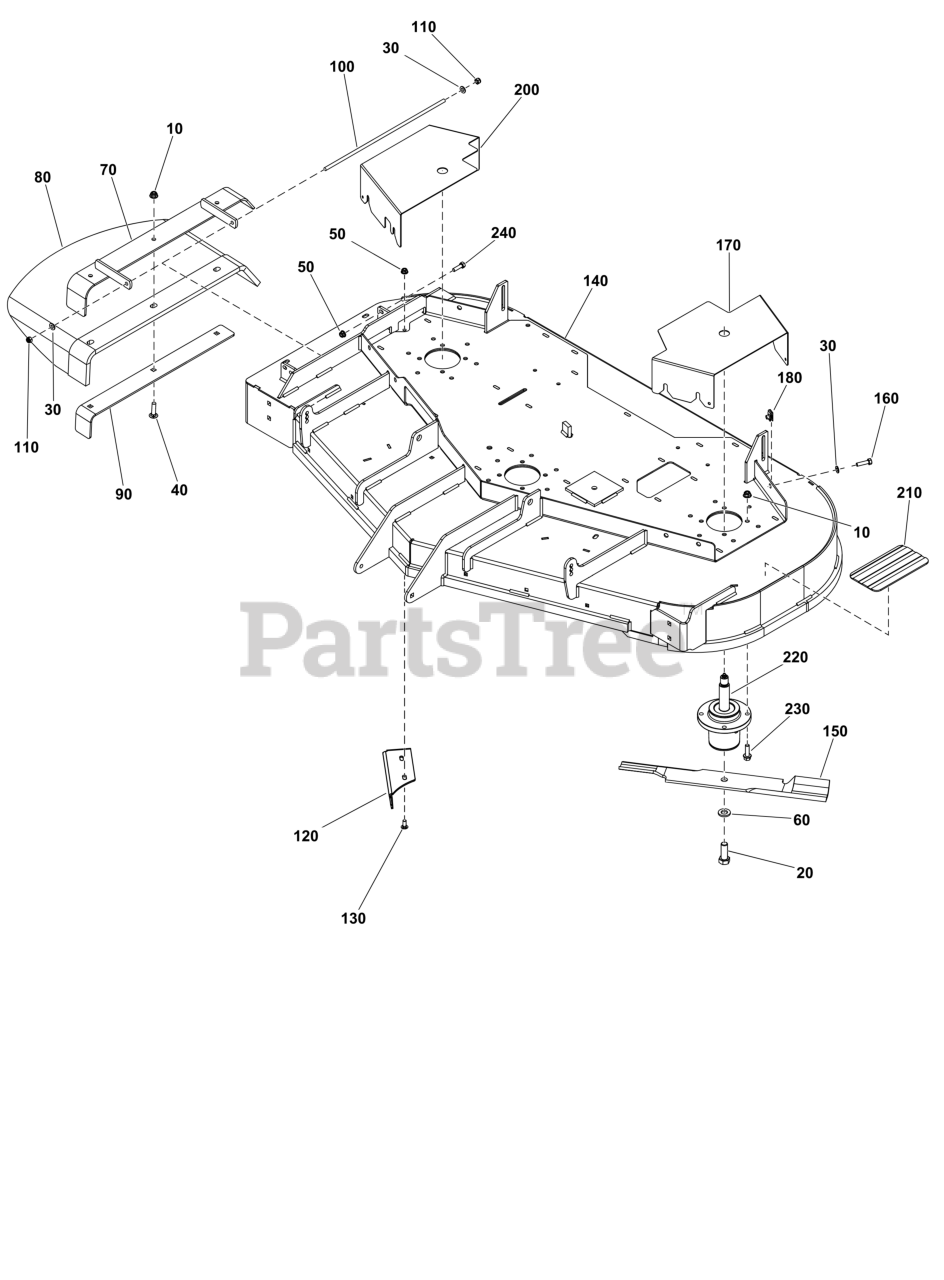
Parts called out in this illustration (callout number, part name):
10	NUT, 3/8-16 HEX NYLOCK
20	BOLT
30	WASHER
40	BOLT, 3/8-16 X 1-1/2
50	NUT
60	WASHER, 5/8" YZ
70	FRAME, Chute
80	CHUTE, RUBBER DISCHARGE (5104442)
90	PLATE, SUPPORT
100	ROD
110	NUT, 5/16-24 HEX NYLO
120	DEFLECTOR
130	BOLT, 5/16-18 X 3/4",
150	BLADE SET, 61 DECK (3)
170	GUARD, LH
180	BODY CLIP, 5/16-18 X
200	GUARD, RH
210	SAFETY WALK
220	ASSM, SPINDLE, LONG S
240	BOLT, 5/16-18 X 3/4"
